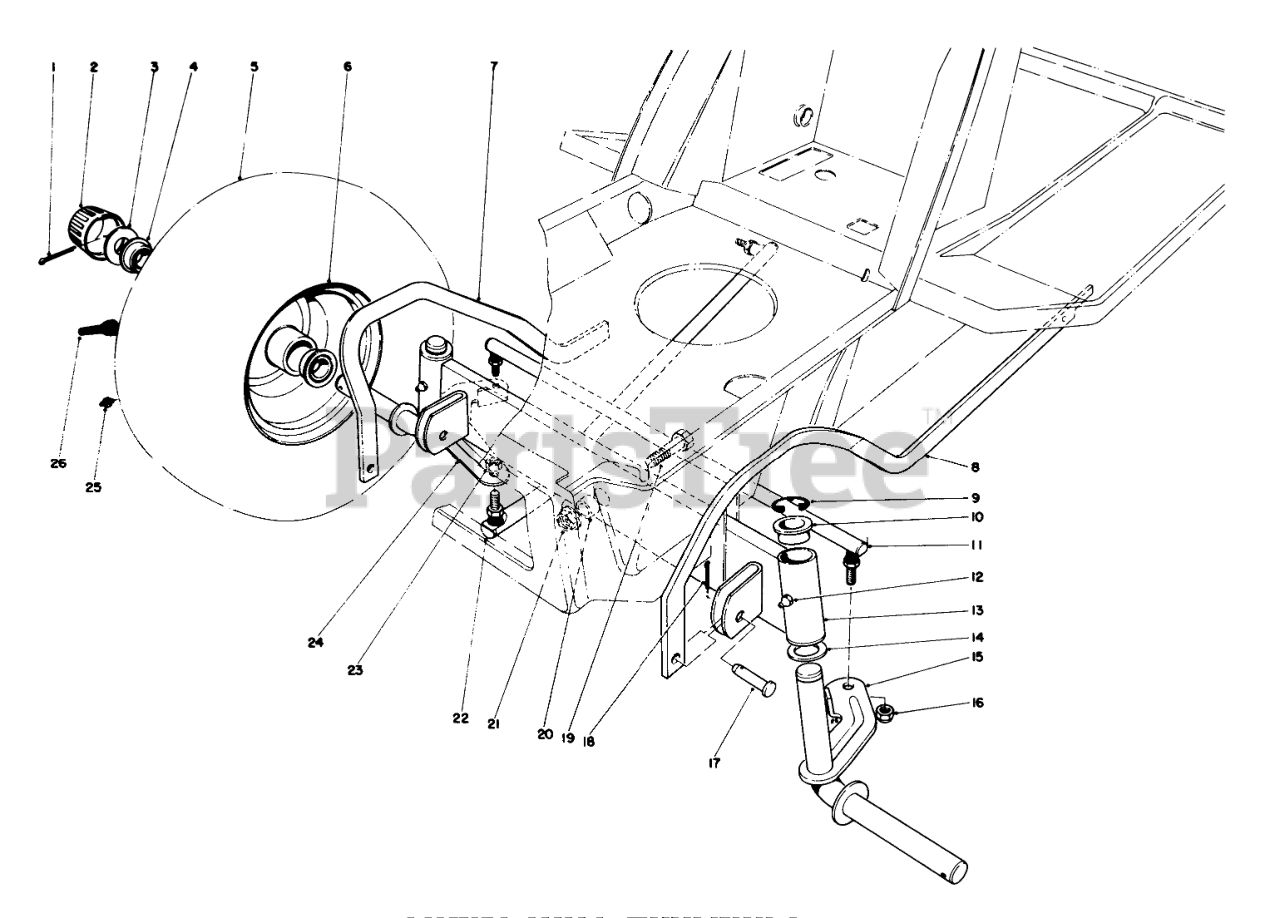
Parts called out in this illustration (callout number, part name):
1	PIN-COTTER
2	Cap-Hub
3	WASHER-PLAIN
4	Bearing
5	TIRE-FRONT
6	FRONT WHEEL
7	RH DECK PARALLEL LINK R
8	LH DECK PARALEL LNKR
9	E-RING
10	BEARING-FLANGE
11	Tie Rod Steering
12	Fitting-Grease
13	Front Axle (Incl. Ref. #10)
14	WASHER-THRUST
15	Spindle L.H.
17	PIN-CLEVIS
18	PIN-COTTER
19	SCREW-HH
20	SPACER-AXLE, FRONT
21	NUT-HF
22	STEERING ARM B
23	Nut
24	SPINDLE WA RH B
25	FITTING-GREASE
26	STEM-VALVE
